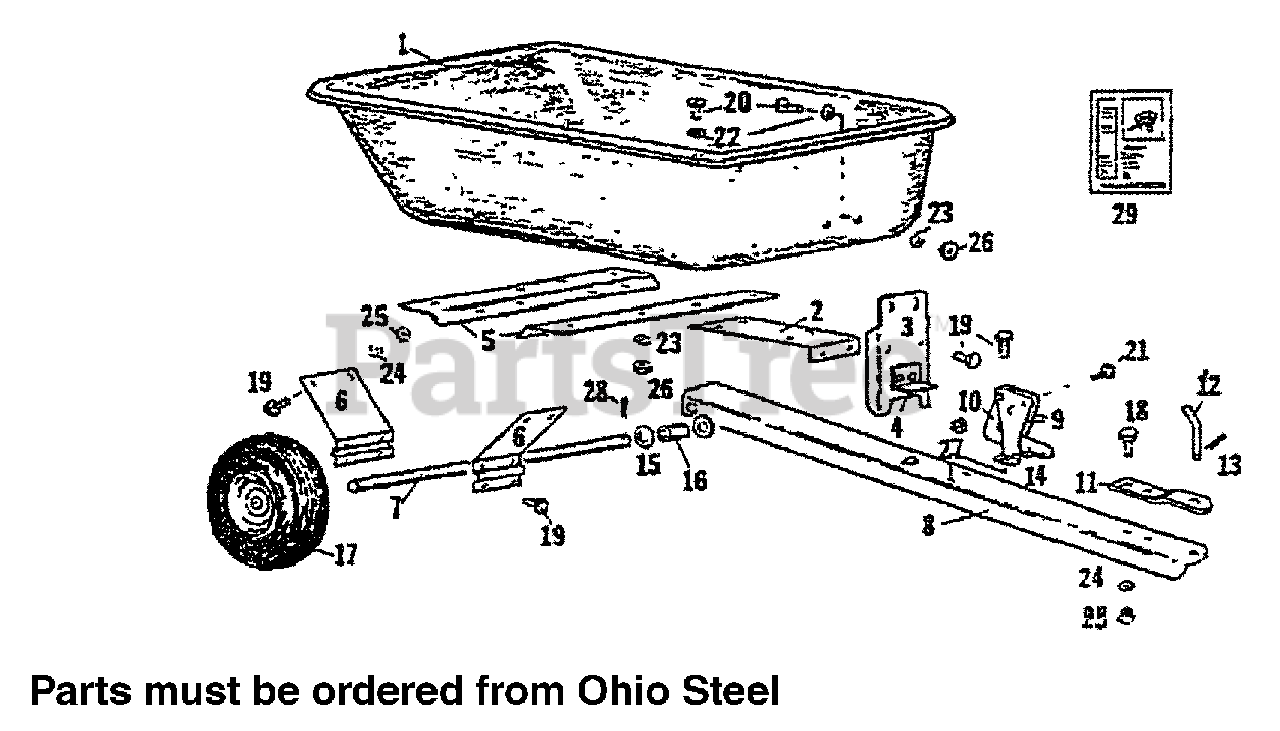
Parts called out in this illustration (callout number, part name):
1	Cart Body
2	Front Support Brace
3	Front Support
4	Latch Angle
5	Axle Support
6	Axle Holder
7	Axle, 3/4"
8	Drawbar
9	Latch Post
11	Hitch Bracket
12	Hitch Pin
13	Hairpin cotter
14	Latch Spring
15	Axle Washer
17	Wheel 4.00 x 6
18	Bolt 3/8 x 1" Hex
19	Bolt 3/8 x 3/4" Hex
20	Bolt 5/16 x 3/4 Pan Rd.
21	Bolt 1/4 x 3/4 Hex
22	Flat Washer 5/16
23	Lock Washer 5/16
24	Lock Washer 3/8
25	Hex Nut 3/8
26	Hex Nut 5/16
27	Lock Nut 1/4
28	Cotter 3/16 x 1-1/2"
29	Owner's Manual
